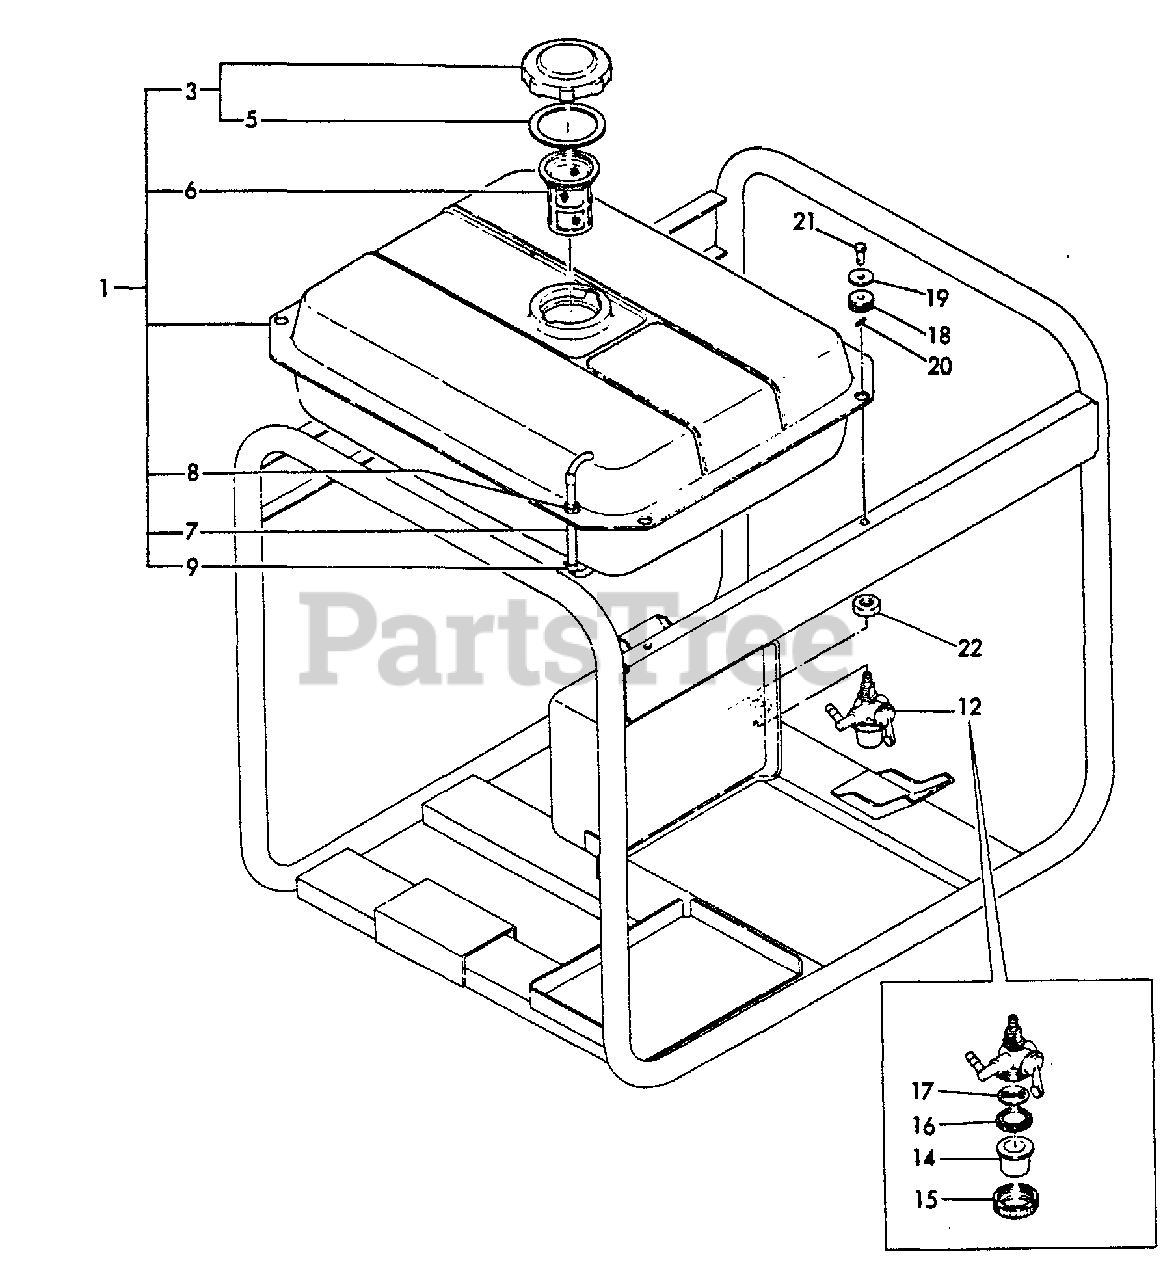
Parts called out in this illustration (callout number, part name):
1	FUEL TANK ASSY
3	CAP ASSY
5	GASKET
6	STRAINER, FUEL
7	PIPE, GAUGE
8	GROMMET
9	CLAMP, HOSE - 9
12	FUEL COCK ASSY
14	BOWL, STRAINER
15	RETAINER
16	GASKET
17	STRAINER, FUEL
18	GROMMET
19	WASHER
20	PIN - 6 -- SNAP
21	PIN - 6X14
22	LOCKNUT - 12
